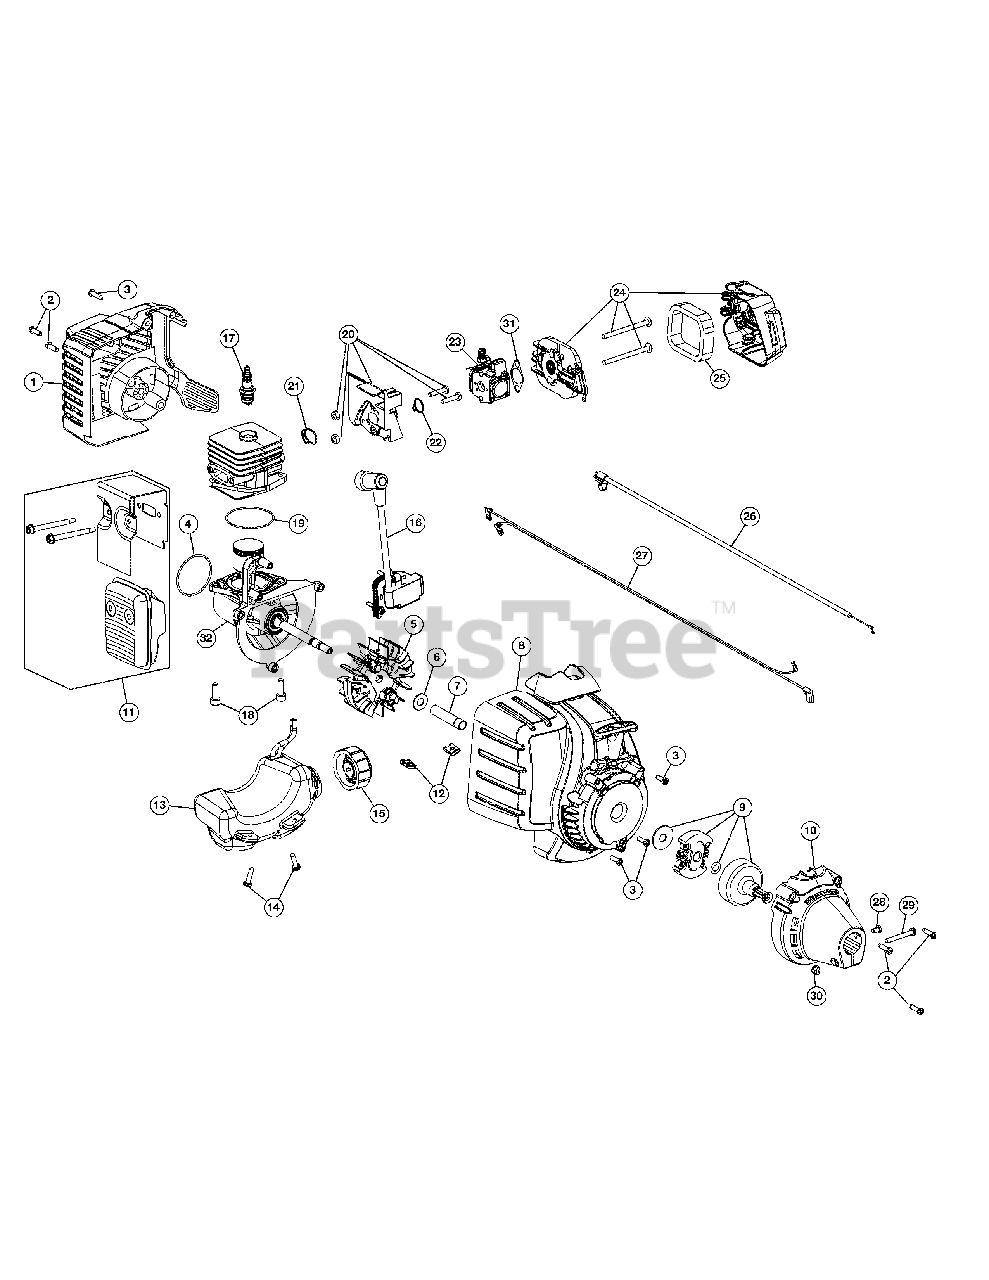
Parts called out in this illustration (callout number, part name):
1	Rear Cover Assembly (Incl. 2 & 3)
2	Housing Screw
3	Cover Screw
4	O-Ring
5	Flywheel Assembly
6	Washer
7	Spacer
8	Starter Housing (Incl. 3 & 12)
9	Clutch Assembly
10	Clutch Cover (Incl. 2)
11	Muffler Assembly
12	U-shaped Nut
13	Fuel Tank Assembly (Incl. 14 & 15)
14	Tank Screw
15	Fuel Cap
16	Module Assembly
17	Spark Plug
18	Crankcase Bolt
19	Crankcase O-Ring
20	Insulator Assembly (Incl. 21 & 22)
21	Insulator O-Ring
22	Carburetor O-Ring
23	Carburetor
24	Aircleaner Cover Assembly (Incl. 25)
25	Aircleaner Filter
26	Throttle Cable
27	Lead Wires
28	Anti-rotation Screw
29	Clamp Screw
30	Clamp Nut
31	Air Cleaner Gasket
32	Short Block Assembly (Incl. 4 - 7 & 16 - 19)
